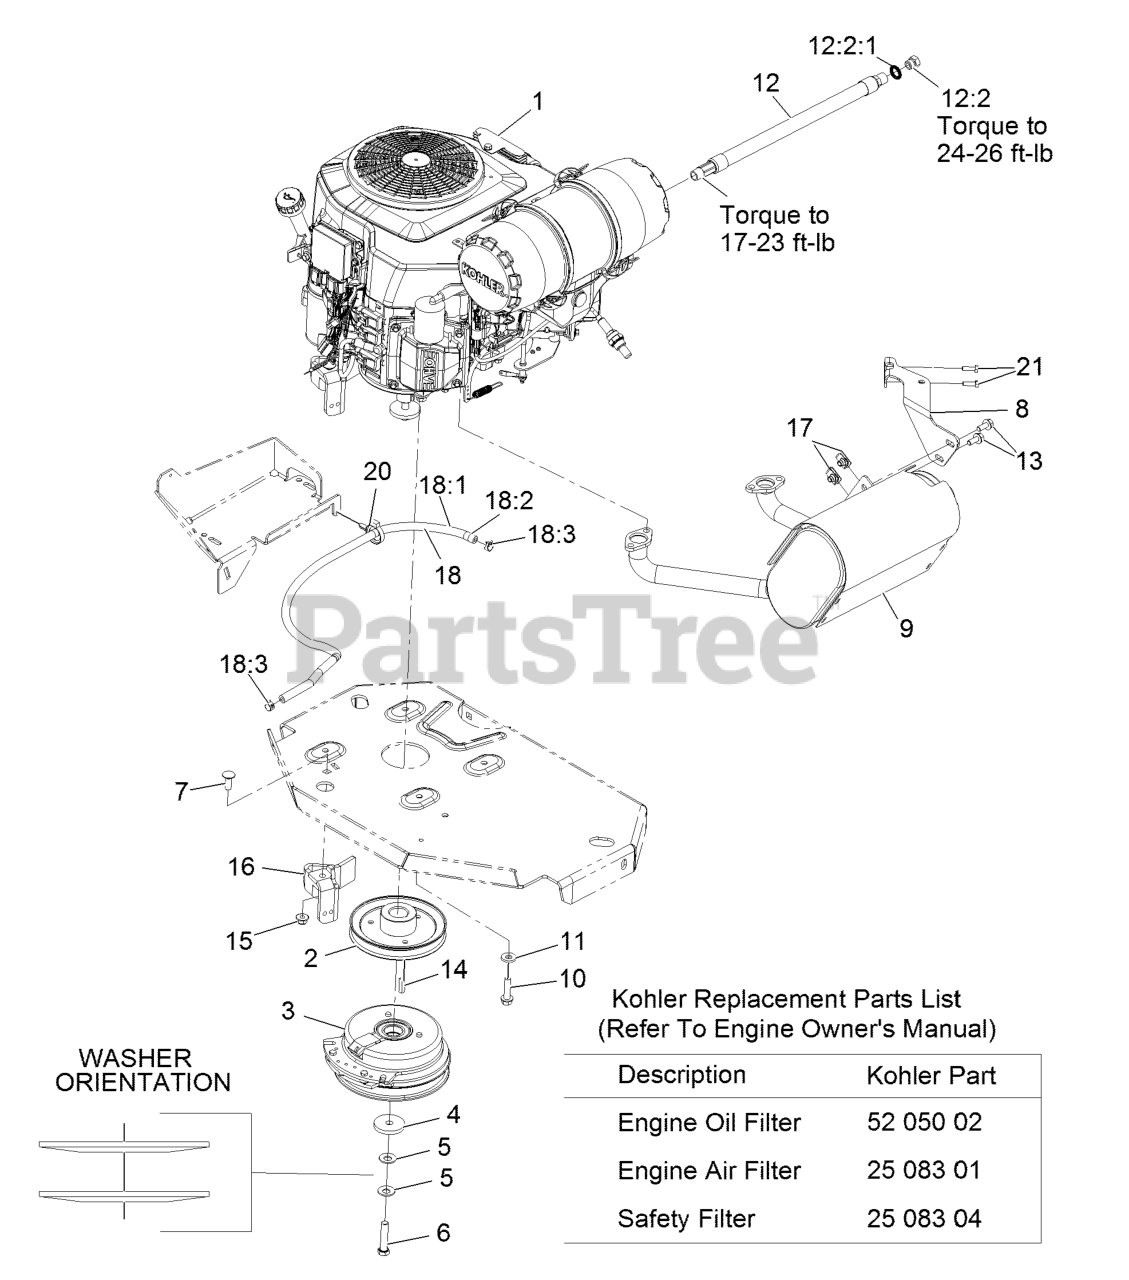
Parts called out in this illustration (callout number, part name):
1	Engine
2	SHEAVE
3	CLUTCH KIT
4	WASHER-CLUTCH
5	WASHER-SPRING
6	SCREW-HH W/LOCTITE
7	SCREW-CARR
8	MUFFLER BRACKET KIT
10	SCREW-HWH
11	WASHER-BELLEVILLE
12	OIL DRAIN HOSE ASM
12:2	PLUG-HH
12:2:1	O-RING
13	SCREW-HHF
15	NUT-HF, NI
16	CLUTCH-ANCHOR
18	FUEL LINE ASM
18:1	HOSE-FUEL
18:2	SLEEVE-THERMAL
18:3	CLAMP-HOSE
20	CLAMP-HOSE
21	SCREW-HH M6-1 X 20Mm W/Patch
